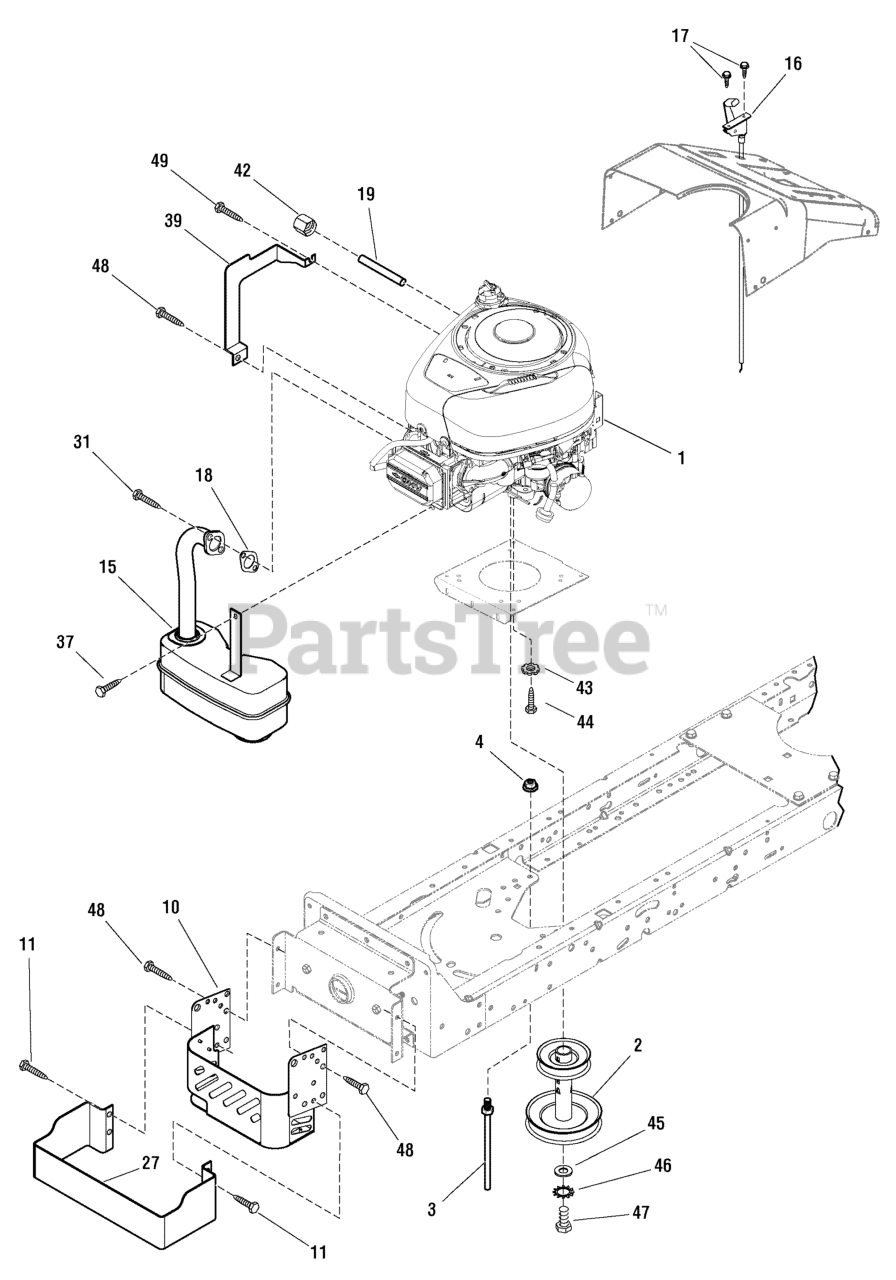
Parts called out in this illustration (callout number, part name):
1	ENGINE, 15.5HP Briggs & Stratton*
2	PULLEY, Stack
3	GUIDE, Belt
4	NUT, Flange, 5/16-18
10	HEAT SHIELD
11	SCREW, 5/16-18 x 1/2
15	MUFFLER ASSEMBLY, Single
16	THROTTLE CONTROL
17	SCREW, Self Tap #8 x 3/8
18	GASKET, Exhaust
19	NIPPLE, Pipe, 3/8 x 3 in
27	GUARD, Heat Shield, Front
31	SCREW, Torx Head 5/16-18 x 5/8
37	SCREW, Thread Forming 1/4-20 x 5/8
39	GUARD, Exhaust Pipe
42	CAP, Pipe 3/8
43	WASHER, Star, 3/8
44	BOLT, 3/8-16 x 1-1/4
45	WASHER, .470- 1.00.25 FLT
46	WASHER, Star, 1/2
47	BOLT, Hex, 7/16-20 x 1-1/2
48	CAPSCREW, 5/16-18 x 3/4
49	SCREW, 5/16-18 WASHER HEX HEAD
